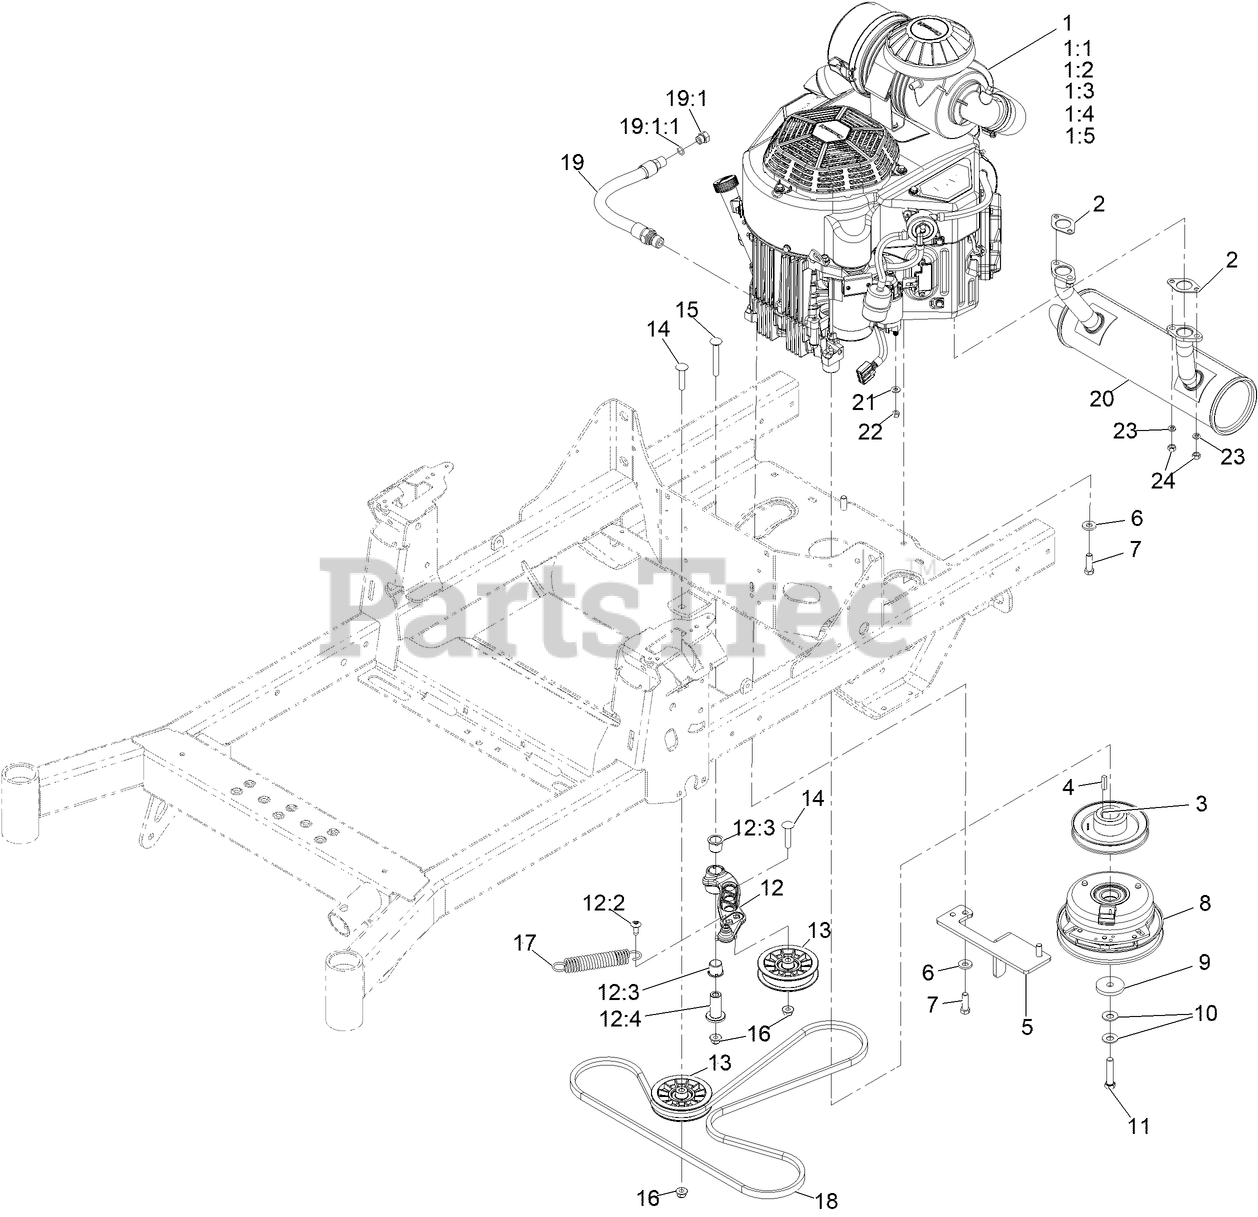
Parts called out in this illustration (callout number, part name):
1:1	Filter-Oil
1:2	Filter-Fuel
1:3	Element-Filter, Air (Inner)
1:4	Element-Filter, Air (Outer)
1:5	SPARK PLUG
2	GASKET-EXHAUST
3	SHEAVE, ENGINE
5	Anchor-Clutch
6	WASHER-BELLEVILLE
7	SCREW-HH
9	WASHER-CLUTCH
10	WASHER-SPRING
11	SCREW-HH W/LOCTITE
12	ASM, PUMP IDLER
12:2	SCREW, TAPTITE
12:3	BUSHING, IGUS
12:4	Spacer, Idler Pivot
13	PULLEY-FLAT IDLER
14	SCREW-CARR
15	SCREW-CARR
16	NUT-HF, NI
17	SPRING-EXTENSION
18	BELT-V
19	ENGINE OIL DRAIN HOSE ASM
19:1	PLUG-HH
19:1:1	O-RING
20	MUFFLER, KAWASAKI
21	WASHER-FLAT
22	NUT-HEX
23	WASHER-LOCK
